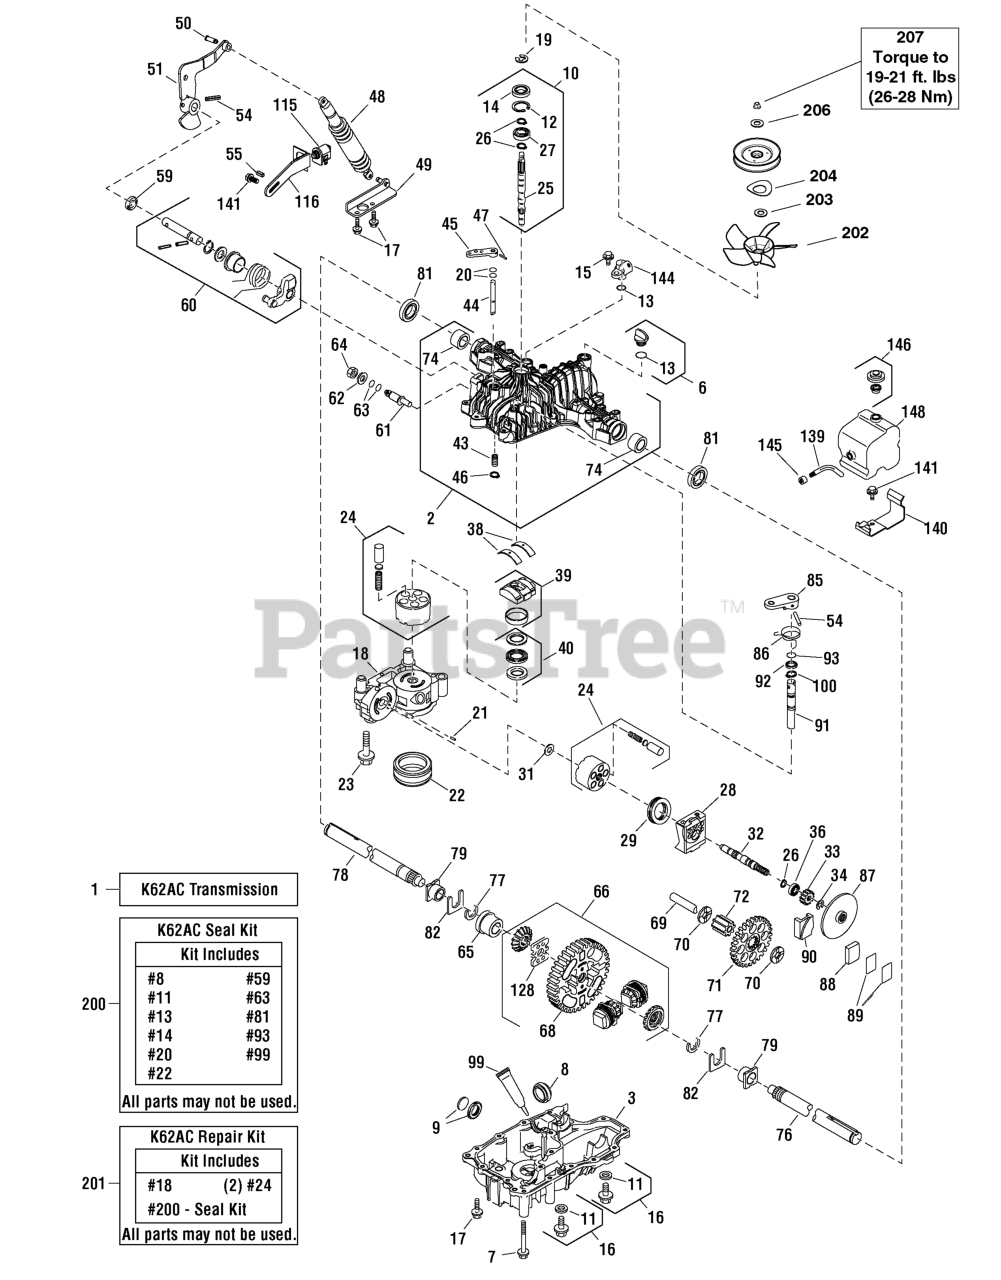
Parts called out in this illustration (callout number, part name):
1	TRANSMISSION, Tuff Torq, K62AC
2	* KIT, Upper Case
3	* CASE, Lower
6	* KIT, Cap
7	M8 * 75 SCREW CAP
11	WASHER SEAL 10
12	SNAP RING C 35
14	SEAL TC 153507
15	M8 * 20 FLANGE BOLT
16	*KIT, Drain Bolt
17	TAPPING SCREW 8 * 30
18	* CENTER CASE A
20	O-RING, 1A P10A
21	PIN 3 * 9.8
24	* KIT, Cylinder Block
25	* PUMP SHAFT
26	E-RING
27	BEARING 6202C3
28	* MOTOR HOUSING
29	THRUST BEARING
31	WASHER 12 * 24 * 1
32	* SHAFT, Motor
34	* E-RING
38	THRUST METAL
39	SWASH PLATE ASSEMBLY
40	* KIT, Thrust Bearing
44	* BYPASS SHAFT
45	BYPASS LEVER
47	SPRING PIN 3.0A * 20
48	SHOCK ABSORBER K65
49	* SHOCK STAY
51	* CONTROL LEVER
54	ROLL PIN 6 * 40
55	* PIN
59	SEAL TC 162606
60	* KIT, Control Shaft
61	* SPRING, Torsion, Strong
63	O-RING 1A P14
66	* KIT, Differential Gear
69	* FINAL PINION SHAFT
70	WASHER 15 * 35 * 3.2
72	FINAL PINION Gear (11T)
74	BUSHING 25.4
76	SHAFT, Axle, LH
77	RETAINING RING 23
78	* AXLE SHAFT, RH
79	BUSHING 25.4
81	SEAL S 25.4 * 42 * 8
82	THRUST WASHER
85	* BRAKE LEVER
86	* BRAKE RETURN SPRING
87	* BRAKE DISC
89	* KIT, Shim
90	* BRAKE ACTUATOR
91	* BRAKE SHAFT
92	WASHER 16 * 23 * 1.6
93	O-RING 1A P12
99	* SEALANT
100	* SNAP RING
115	* ROS SWITCH
116	* ROS SWITCH PLATE
128	* DIFFERENTIAL LOCK PLATE, 19 Holes
139	* PIPE
140	* TANK BRACKET
144	* FITTING
146	VENT VALVE 15
148	RESERVOIR TANK
201	* KIT, Repair (K62A,B,C,E,F,G,J & K)
203	WASHER, Flat
204	WASHER, Wave, 0.65" ID
206	WASHER, Flat
207	NUT, Hex Flange, M10-1.5, Nylon Insert
